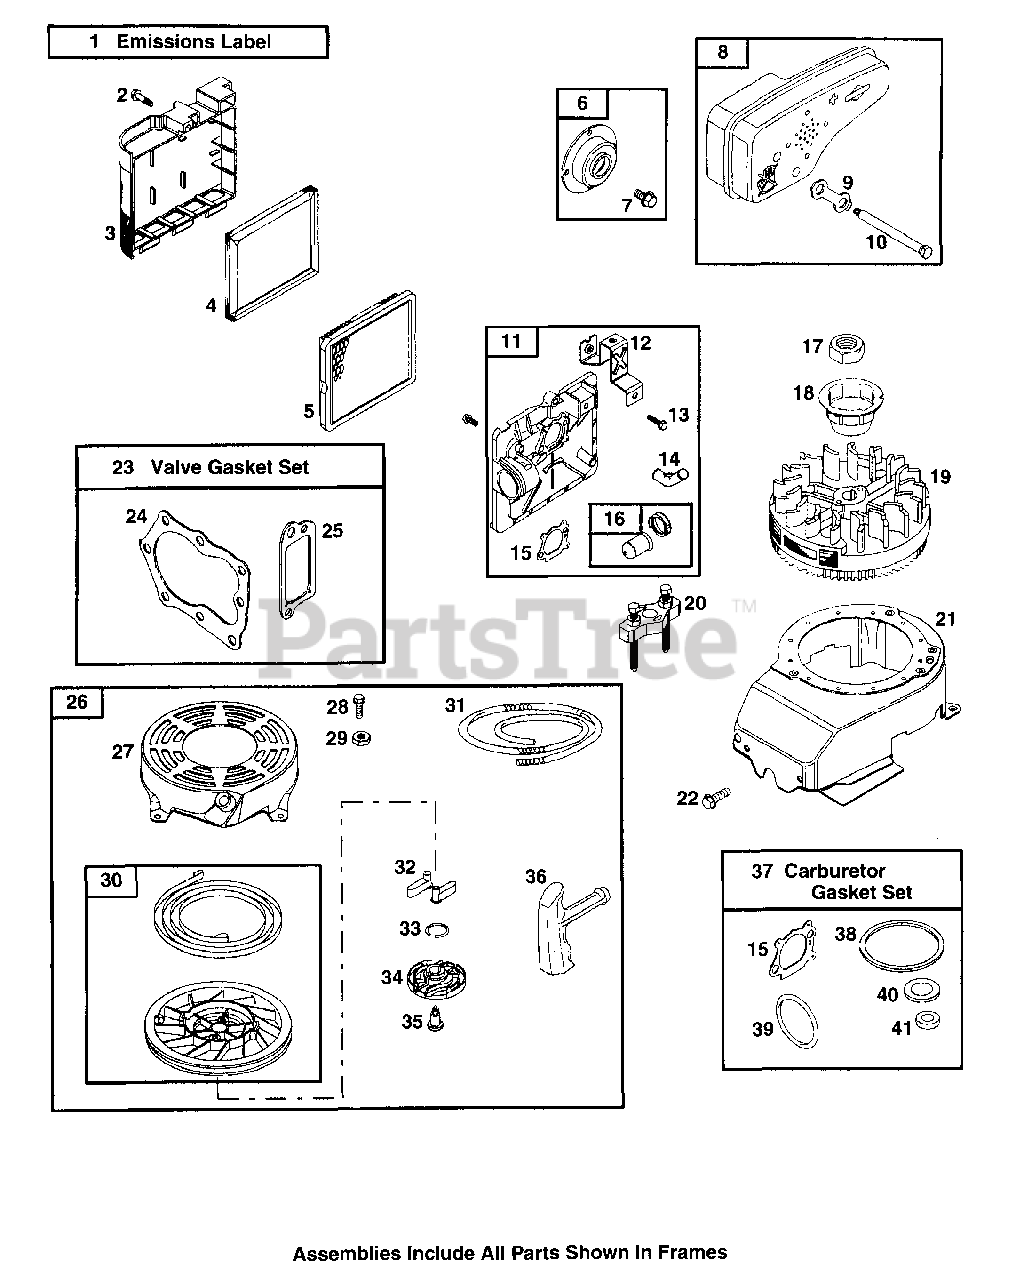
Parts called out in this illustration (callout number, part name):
1	Emissions Label
2	Screw (Air Cleaner Cover)
3	Air Cleaner Cover
4	Pre-Cleaner Filter
5	Air Cleaner Cartridge Filter
6	Muffler Deflector
7	Screw (Muffler Deflector)
8	Exhaust Muffler
9	Muffler Screw Lock
10	Screw (Exhaust Muffler)
11	Air Cleaner Primer Base
12	Air Cleaner Primer Bracket
13	Screw (Air Cleaner Primer Bracket)
15	Air Cleaner Gasket
16	Carburetor Primer
17	Nut (Flywheel)
18	Flywheel Cup
20	Flywheel Puller
21	Blower Housing
22	Screw (Blower Housing)
23	Valve Gasket Set
24	Cylinder Head Gasket
25	Breather Gasket
26	Rewind Starter
27	Rewind Starter Housing
28	Screw (Rewind Starter)
29	Nut (Rewind Starter Housing)
30	Pulley/Spring Assembly
31	Starter Rope
32	Ratchet Pawl
33	Friction Spring
34	Pawl Friction Plate
35	Screw (Pawl Friction Plate)
36	Starter Rope Grip
37	Carburetor Gasket Set
38	Float Bowl Gasket
39	O-Ring Seal (Intake Manifold)
40	Sealing Washer
41	Locating Pin
